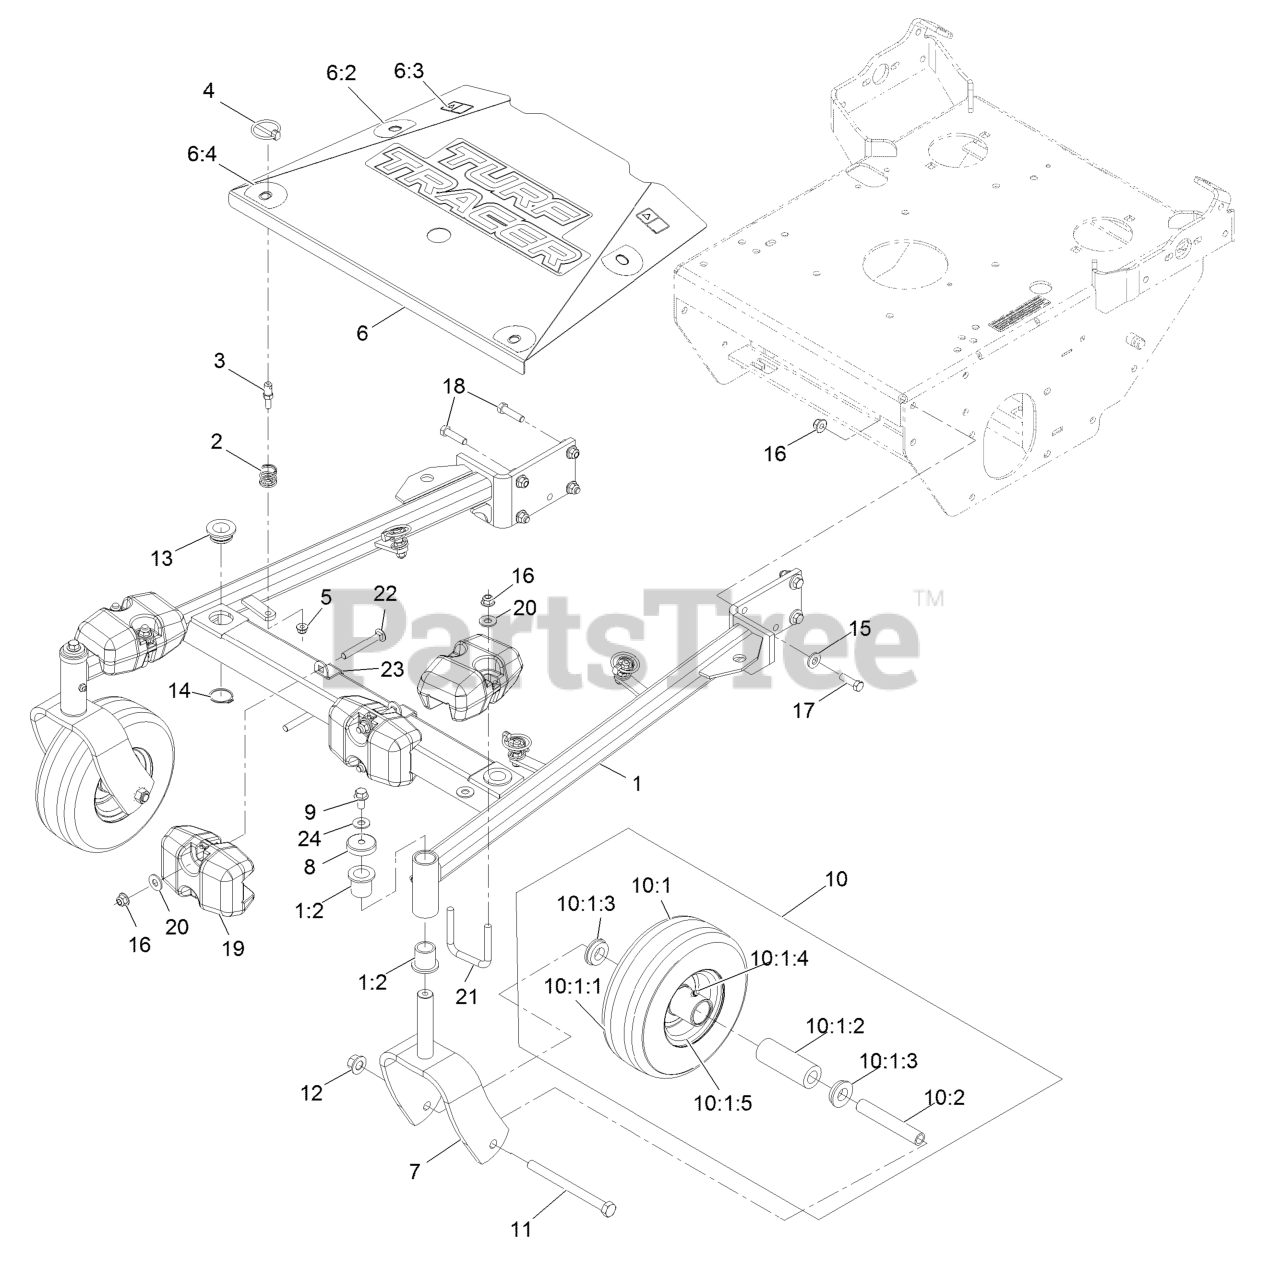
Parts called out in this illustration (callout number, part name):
1	ASM, Frame W/ Bushings,48
1:2	Bearing-Flanged
3	Pin-Spring
4	Pin-Lynch
5	Nut-Nyloc 5/16-18 Flg
6	ASM, Shield W/ Decals, 48
6:2	Decal-Turf Tracer
6:3	Decal-Warning
6:4	Decal-Scratch Cover
7	Fork, Caster [red]
8	Cap, Dust
9	Screw-Hex Flange 3/8-16 X 3/4
10	Kit,Semi-Pneumatic Wheel Replacement
10:1	Wheel And Tire ASM
10:1:1	Tire
10:1:2	Bearing
10:1:3	Bushing-Flanged
10:1:4	Zerk-45deg 1/4-28
10:1:5	Wheel
11	Screw-HH 1/2-13 X 6
12	Nut-Lock 1/2-13
13	Bushing-Deck
14	Ring-Retaining
15	Washer-Spring Disc 3/8
16	Nut-Nyloc 3/8-16 Flg
17	Screw-HH 3/8-16 X 1 1/4
18	Screw-HH 3/8-16 X 1 1/2
19	Weight-Support, Caster
20	Washer-Flat
22	Screw-CARR
23	Strap, Weight
